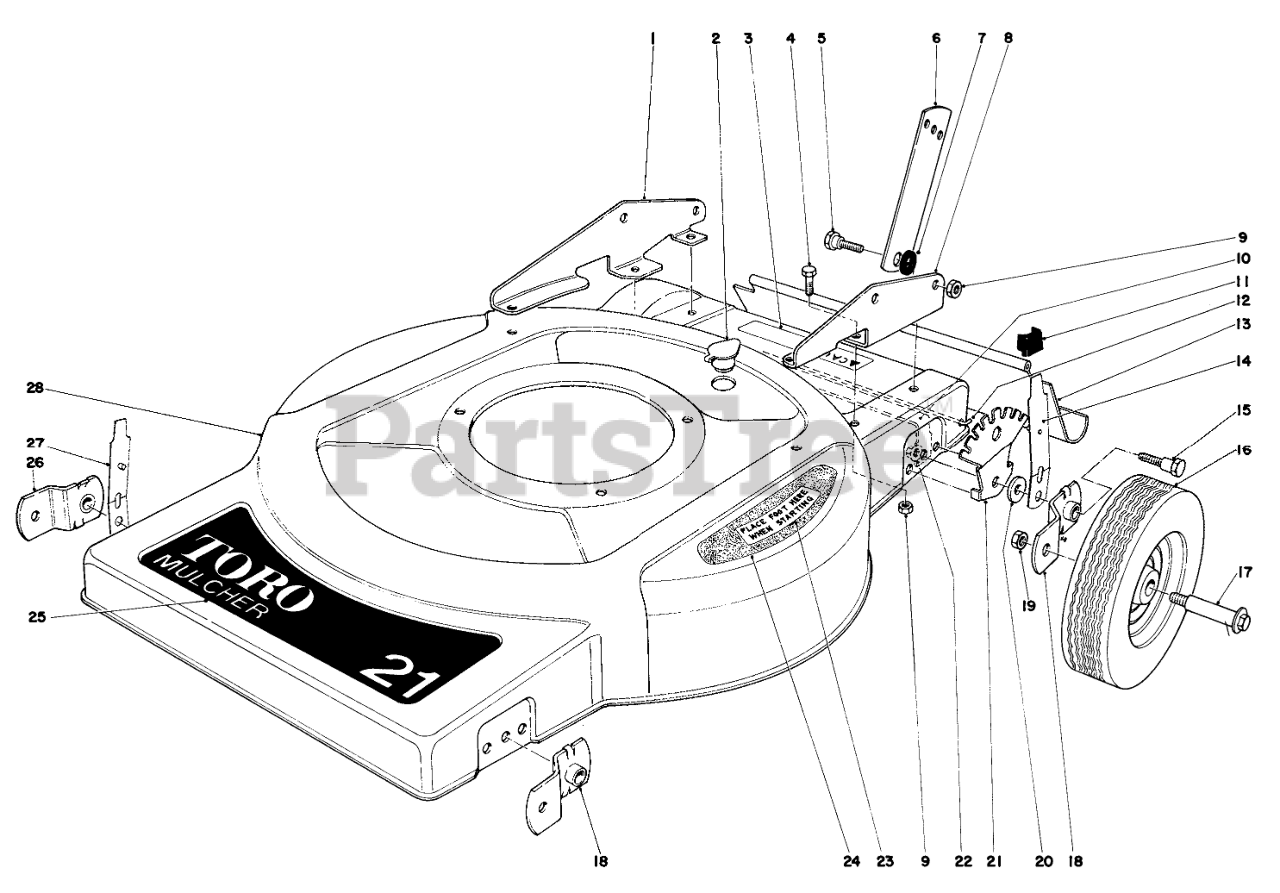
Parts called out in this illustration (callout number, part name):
1	Bracket Handle R.H.
2	WASHOUT PLUG
3	Caution Decal
4	SCREW-HH
5	SCREW-SHOULDER
6	Handle Latch
7	SPACER
8	Bracket Handle L.H.
9	NUT-LOCK, CONE
10	DECK SUPPORT
11	KNOB-ARM
12	SHIELD ROD
13	SHIELD - TRAILING
14	SPRING ARM ASM
15	PIVOT SCREW
16	Wheel Assembly
18	PIVOT ARM ASM A
19	Nut
20	PIVOT WASHER
21	Quadrant
23	Decal Step Pad
24	PAD STEP
25	Decal-Front Deck
26	PIVOT ARM ASM B
27	SPRING ARM ASM
28	Housing
